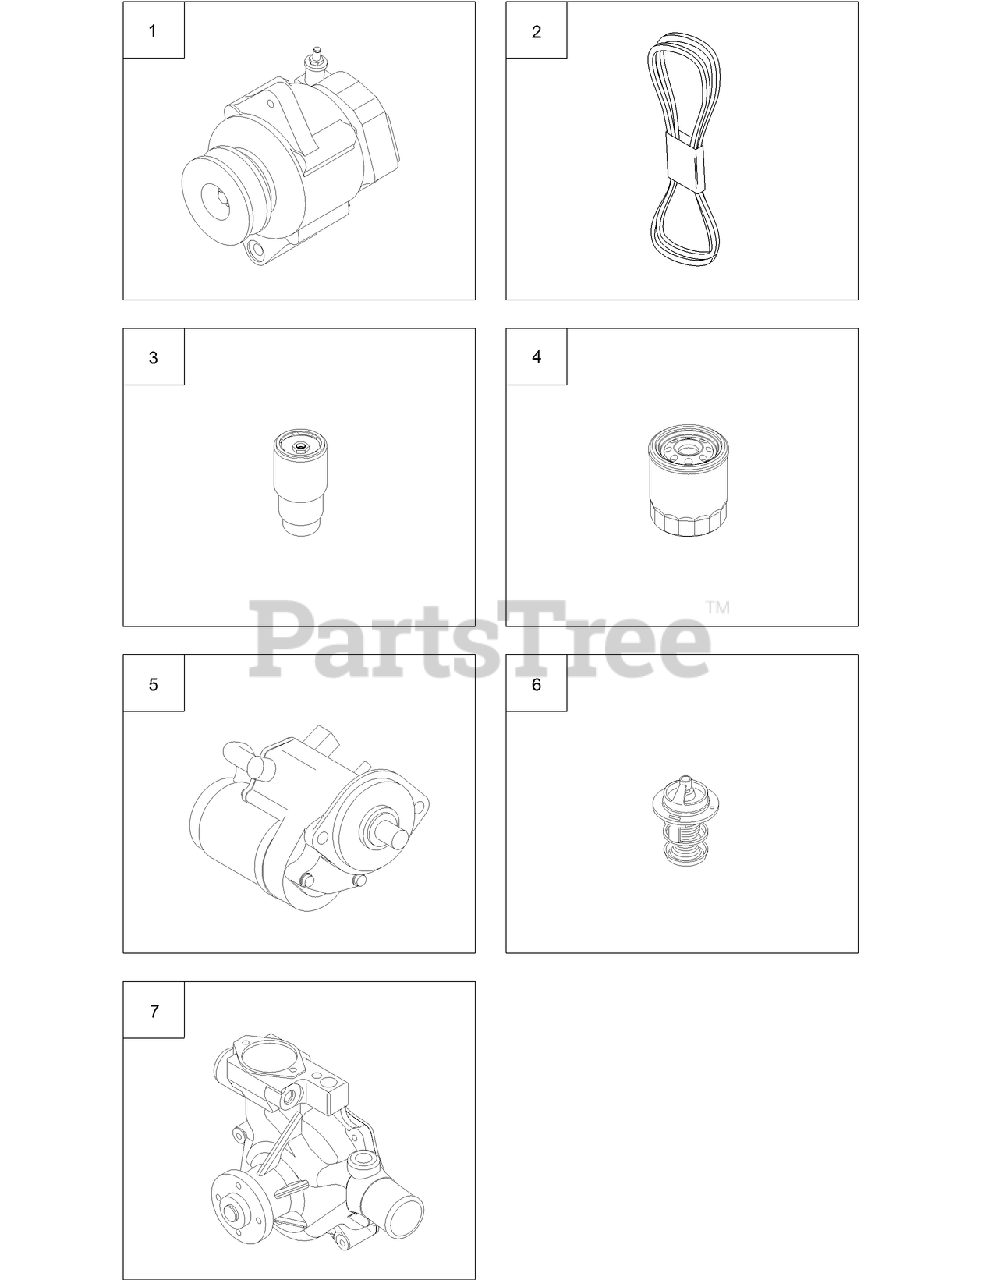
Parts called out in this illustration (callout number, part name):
1	ALTERNATOR
3	FILTER-FUEL
4	FILTER-OIL, ENGINE
5	STARTER
6	THERMOSTAT
7	WATER PUMP
